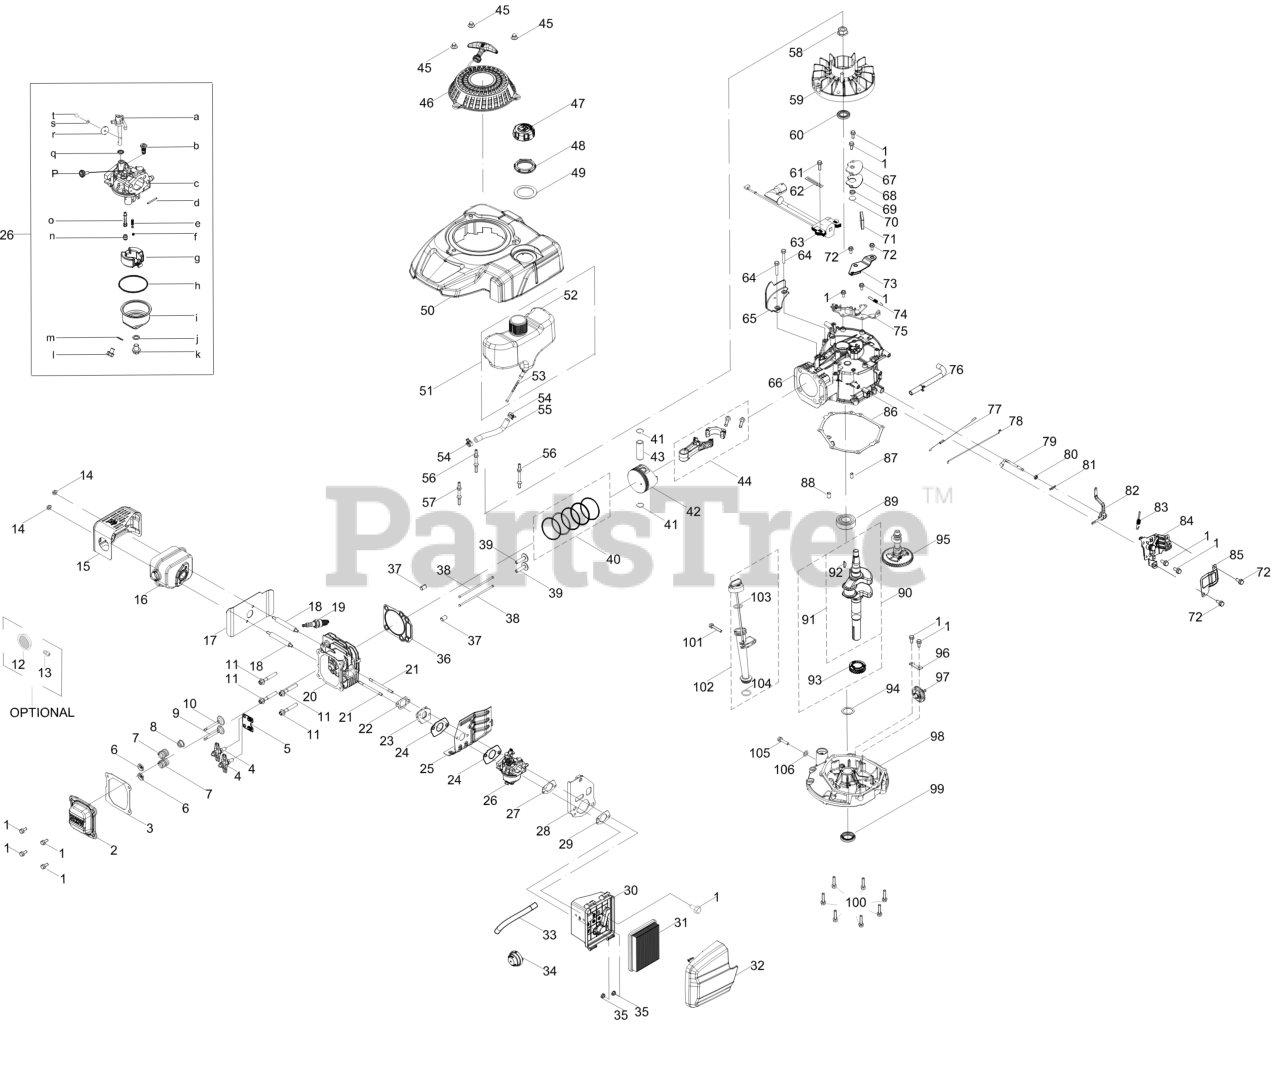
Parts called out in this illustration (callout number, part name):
1	BOLT M6-1 x 14 GR8.8
2	VALVE COVER
3	VALVE COVER GASKET
4	ROCKER ARM ASSEMBLY
5	PUSH ROD GUIDE
6	INTAKE VALVE SPRING RETAINER
7	VALVE SPRING
8	INTAKE VALVE SEAL
9	EXHAUST VALVE
10	INTAKE VALVE
11	SCREW M8 x 54 GR10
12	SPARK ARRESTOR
13	SCREW M3.5 x 9.5
15	MUFFLER SHIELD
17	MUFFLER GASKET
18	STUD M6-1 x 95
19	SPARK PLUG
20	CYLINDER HEAD
21	CARBURETOR STUD-M6 x 87
22	CARBURETOR GASKET
23	CARBURETOR INSULATOR
24	CARBURETOR GASKET
25	HEAT SHIELD
26	CARBURETOR
27	AIR FILTER BRACKET GASKET
28	AIR FILTER BRACKET
29	AIR FILTER BASE GASKET
30	AIR FILTER BASE
31	AIR FILTER
31	Cub Cadet AIR FILTER
31	Genuine Factory Parts AIR FILTER
32	AIR FILTER COVER
33	PRIMER HOSE
34	VENTED PRIMER ASSEMBLY
36	CYLINDER HEAD GASKET
40	PISTON RING 4PC SET
41	PISTON PIN SNAP RING
44	CONNECTING ROD ASSEMBLY
45	ACORN NUT
46	RECOIL STARTER ASSEMBLY
47	FUEL CAP ASSEMBLY
48	FUEL TANK NUT
49	FUEL TANK UPPER GROMMET
50	ENGINE SHROUD
51	Fuel Tank Assembly
53	FUEL FILTER
53	Genuine Factory Parts FUEL FILTER
54	HOSE CLAMP
55	FUEL HOSE
56	STARTER/SHROUD REAR STUD
57	STARTER/SHROUD FRONT STUD
58	FLYWHEEL NUT
59	FLYWHEEL
60	CRANKSHAFT SEAL
61	BOLT M6-1 x 20 GR8.8
62	FLEXIBLE CLAMP
63	IGNITION COIL ASSEMBLY
64	BOLT M6-1 x 25 GR8.8
65	ENGINE BRAKE COVER PLATE
67	BREATHER COVER PLATE
68	BREATHER GASKET
69	BREATHER VALVE SPRING
70	BREATHER VALVE
71	BREATHER SCREEN
72	BOLT M6-1 x 12 GR8.8
73	AIR VANE COVER
74	ENGINE BRAKE SPRING
75	ENGINE BRAKE ASSEMBLY
76	BREATHER HOSE ASSEMBLY
77	THROTTLE LINKAGE SPRING
78	THROTTLE LINKAGE
79	GOVERNOR ARM SHAFT
82	GOVERNOR ARM ASSEMBLY
83	Governor Spring
84	VARIABLE SPEED CONTROL ASSEMBLY
85	VARIABLE SPEED CONTROL COVER
86	CRANKCASE COVER GASKET
87	DOWEL PIN 7 X 14
88	DOWEL PIN 9 X 14
90	CRANKSHAFT
91	CRANKSHAFT
92	WOODRUFF KEY
93	DRIVE TIMING GEAR
94	THRUST WASHER
95	CAMSHAFT ASSEMBLY
96	GOVERNOR GEAR MOUNTING PLATE
97	GOVERNOR GEAR/SHAFT ASSEMBLY
98	CRANKCASE COVER
99	LOWER CRANKSHAFT OIL SEAL
100	BOLT-M6-1 x 28 GR8.8
101	BOLT M6-1 x 35 GR8.8
102	OIL DIPSTICK ASSEMBLY
103	O-RING
105	OIL DRAIN PLUG
106	FLAT WASHER
